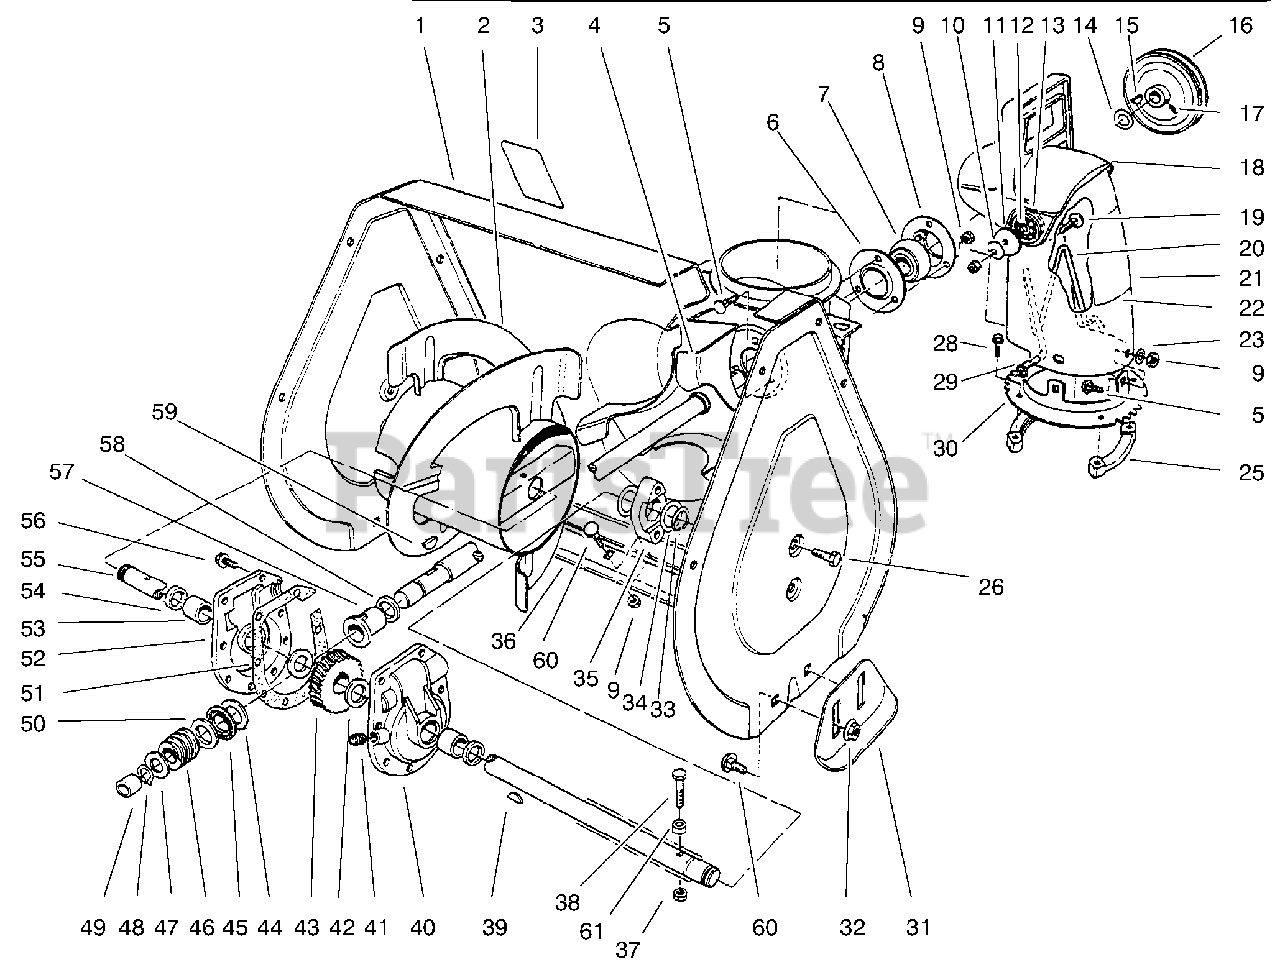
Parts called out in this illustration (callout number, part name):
1	Housing-Auger (Incl. Ref. #3) (Model 28230)
2	Auger-R.H.
3	Decal
4	Shaft & Impeiler
5	SCREW-CARR
6	FLANGE-CUP, BEARING
7	BEARING-BALL
8	FLANGE-CUP, BEARING
9	NUT-LOCK, NI
10	WASHER-BELLEVILLE
11	WASHER-FLAT
12	PLATE-FRICTION
13	WASHER-RUBBER
15	KEY-WOODRUFF
17	SCREW-SET, SQH
18	CHUTE-DEFLECTOR
19	SCREW-CARR
20	WIRE-CHUTE
21	Chute-Discharge (Incl. Ref.# 22) (Model 28230 Only)
22	DECAL-DANGER
23	WASHER-FLAT
25	RING-CHUTE, RETAINER
28	SCREW-SPECIAL
30	Chute Ring
33	RING-RETAINING
35	BEARING-AUGER
36	SCRAPER BLADE (GREEN)
37	NUT-LOCK, NI
38	SCREW-HH
39	KEY-WOODRUFF
40	Gear Case L.H. (Incl. Ref. #53 & 54)
41	PLUG-PIPE, SQH
42	WASHER THRUST 1.010ID 1.552 OD .09WD
43	GEAR-WORM 27T
44	WASHER-THRUST
45	BEARING-THRUST
47	WASHER-THRUST
48	Ring-Snap
49	BUSHING
50	WASHER-THRUST
51	GASKET-GEAR BOX
52	Gear Case R.H. (Incl. Ref. #53 & 54)
54	SEAL-OIL
55	SHAFT-AUGER
56	SCREW-TAPTITE
57	BUSHING-INPUT
58	RING-QUAD
59	KEY-WOODRUFF
60	SCREW-CARR
61	SPACER-HUB, AUGER
